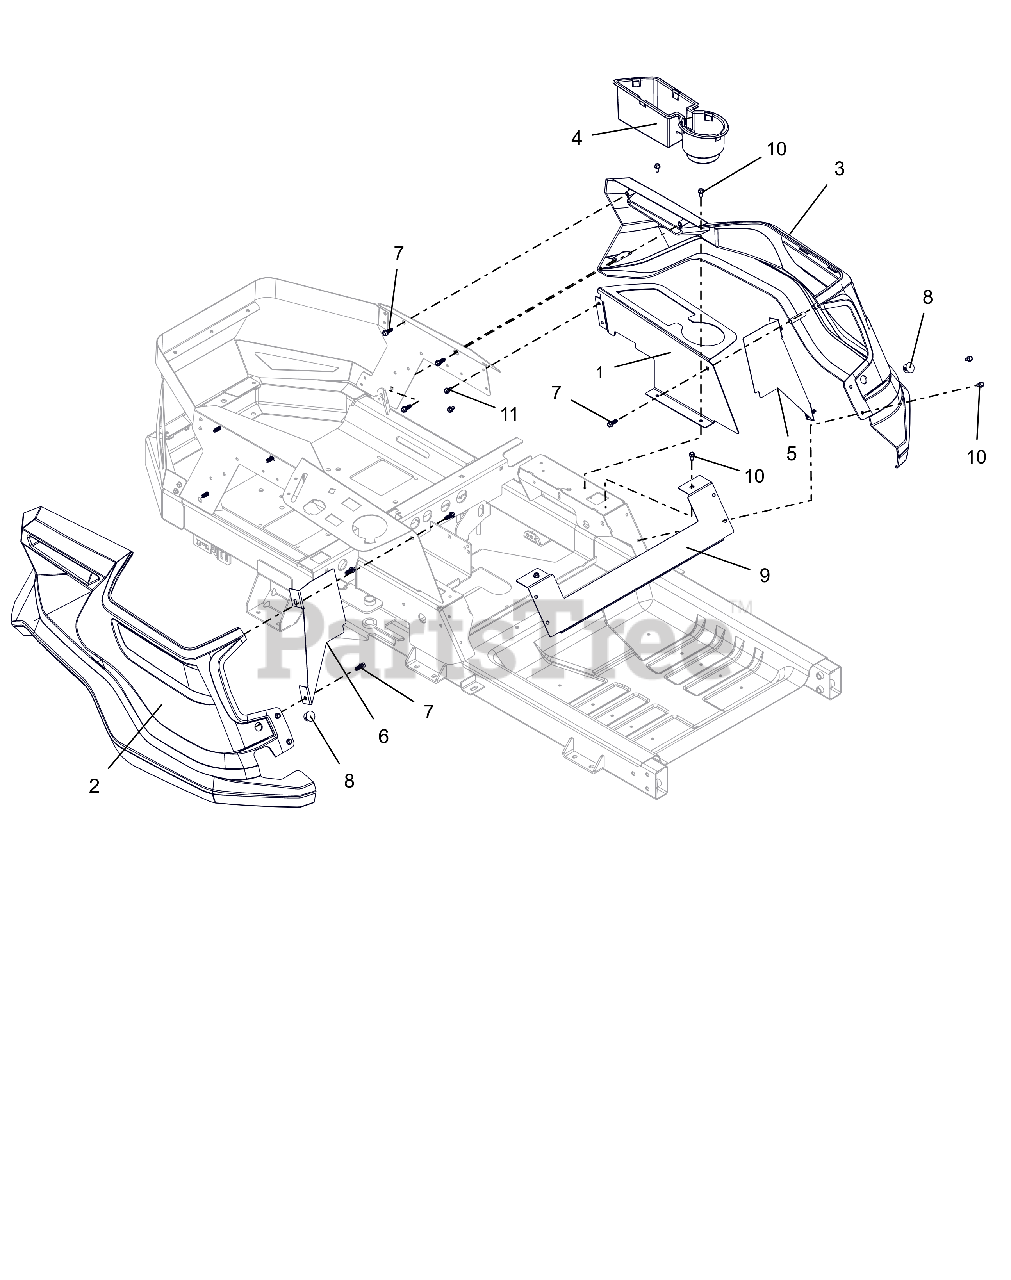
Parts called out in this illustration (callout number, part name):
1	PANEL, LEFT SIDE FENDER MOUNT
2	FENDER, RH IKON
3	FENDER, LH IKON
4	INSERT, CUP/STORAGE HOLDER
5	PLATE, LH BLOCKER
6	PLATE, RH BLOCKER
7	SCR-.312X.75 #14H H/W/H H/L CZ
8	PLUG, HOLE .75 (BLACK)
9	PLATE, SEAT KICK
10	SCR-TAP .25-20X.50 HWH ZCC
11	SCR,TAP .25-20X.375 HWH TR ZCC
